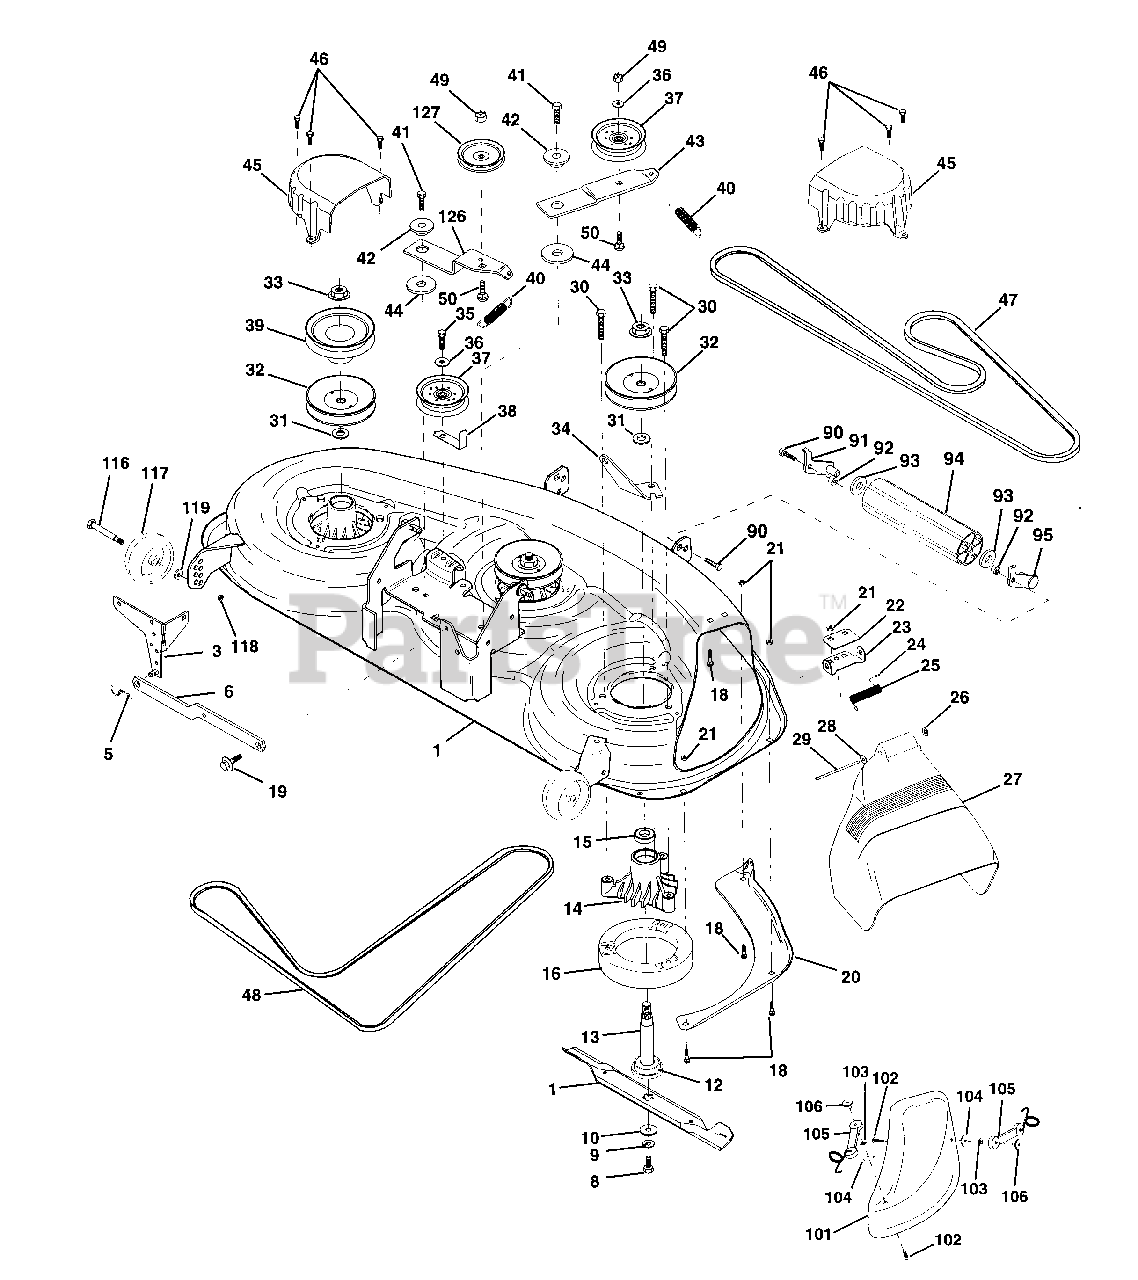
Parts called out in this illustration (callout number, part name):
1	Deck Asm., Mower 46"
3	Bracket Asm., Sway Bar
5	Retainer Spring
6	Arm, Suspension, Rear (Sway Bar)
8	Bolt, Patched 3/8-24 x 1-1/4 Gr. 8
9	Washer, Lock Hvy., Unplated 3/8
10	Washer, Hard Blade, Mower Vented
11	Blade, 46" Mower Deck
12	Bearing, Ball, Mandrel #6204
13	Shaft Asm. w/Lower Bearing
14	Housing, Mandrel
15	Bearing, Ball, Mandrel
16	Stripper, Mower Round
18	Bolt, Carriage 5/16-18 x 5/8
19	Bolt, Hex Head, Shoulder 5/16-18
20	Baffle, Vortex Mower 46"
21	Nut, Crownlock 5/16-18 UNC
22	Stiffiner, Bracket
23	Bracket, Deflector
24	Cap, Sleeve
25	Spring, Torsion, Deflector
27	Shield, Deflector Mower
28	Washer 11/32 x 5/8 x 16 Ga.
29	Rod, Hinge
30	Screw, Hex Head, Thdroll
31	Washer, Spacer Mower Vented
32	Pulley, Mandrel
33	Nut, Flg. Top Lock Cntr. 9/16
34	Anchor, Spring Deck 46"
35	Screw, Thdroll 3/8-16 x 1-3/4 Tytt
36	Washer 13/32 x 13/16 x 16 Ga.
37	Pulley, Idler, Flat
38	Keeper, Belt, Idler
39	Pulley, Idler, Driven
40	Spring, Secondary 44/46/50 Vent
41	Screw, Thdroll 3/8-16 x 1-1/4 Tytt
42	Spacer, Retainer
43	Arm, Idler Secondary
44	Washer, Hardened
45	Cover, Mandrel Deck
46	Screw, Thdroll. 1/4-20 x 5/8
47	V-Belt, Mower, Secondary
48	V-Belt, Mower, Primary
49	Nut, Crownlock 3/8-16 UNC
50	Bolt, Carriage 3/8-16 x 1-1/2 Gr. 5
90	Bolt Fin Hex 3/8-16 x 1
91	Bracket Asm Noseroller LH
92	Nut Lock Hex W/Ins 3/8-16 UNC
93	Washer 17/32 x 7/8 x 16 Ga.
94	Roller Nose
95	Bracket Asm Noseroller RH
101	Cover, Mulching
102	Screw
103	Washer, Lock #10
105	Latch Asm. Bagger
106	Nut, Weld
116	Bolt, Shoulder
117	Gauge Wheel, Wide
118	Nut, Centerlock 3/8-16 UNC
119	Washer 3/8 x 7/8 x 14 Ga.
126	Arm, Idler, Primary Deck 46"
127	Pulley, Idler, V-Groove Dim. 4.25
128	Shield, Idler
129	Keeper, Belt, Idler 46"
